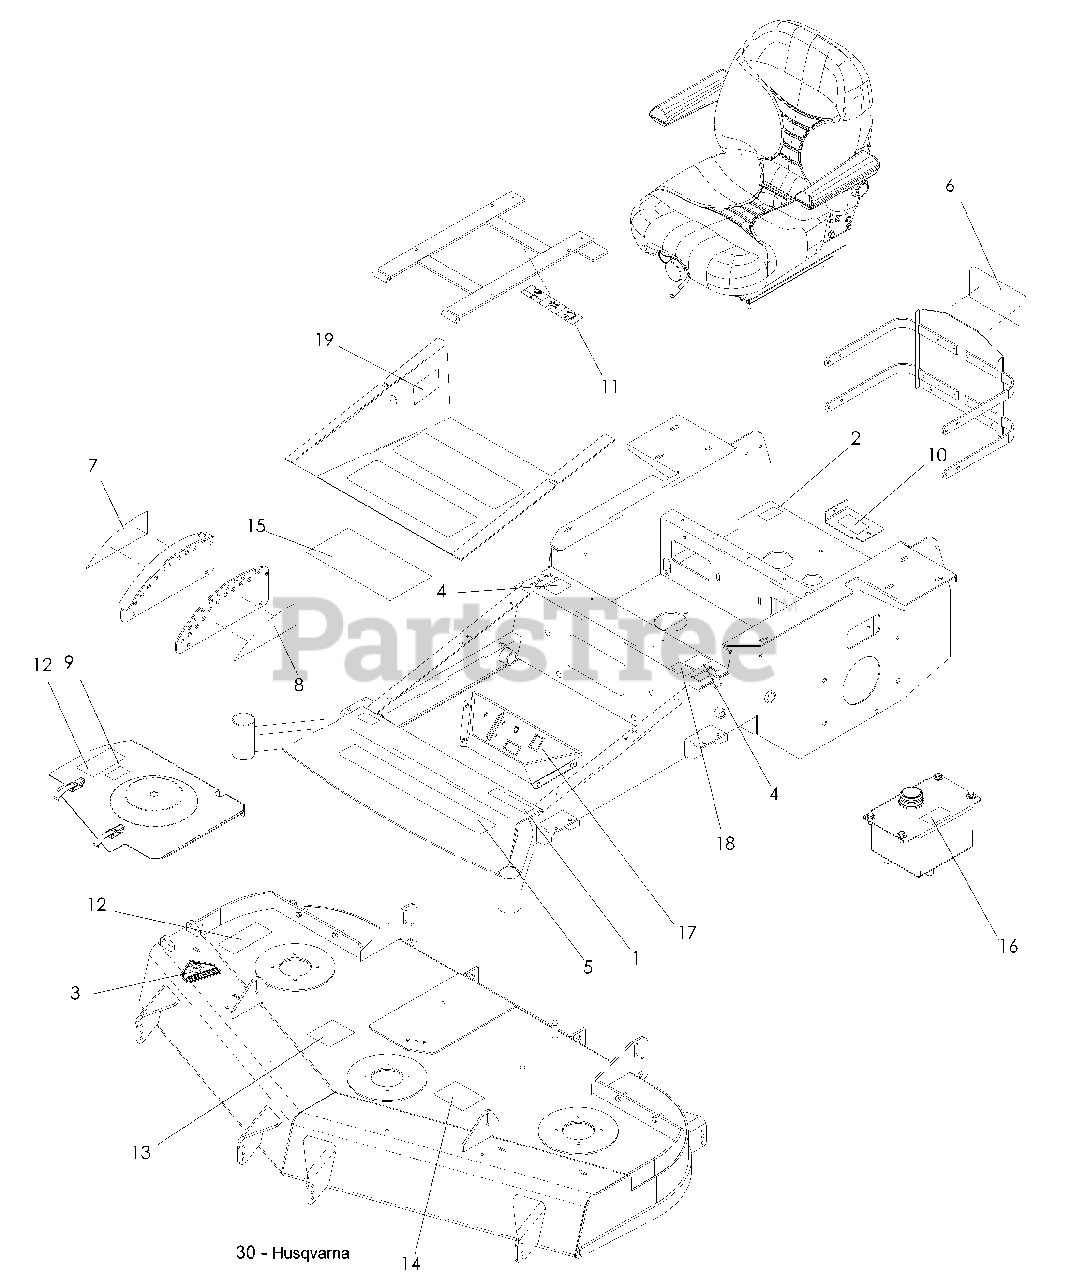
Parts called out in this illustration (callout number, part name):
1	DECAL, LZ5227
2	DECAL, PROP 65
3	DECAL, WARNING
4	DECAL, MOTION CONTROL
5	DECAL, HUSQVARNA
6	DECAL, HUSQVARNA CRWN
7	DECAL, HEIGHT INDICATOR
8	DECAL, HEIGHT INDICATOR
9	DECAL, NO STEP
10	DECAL, DANGER BELT DR
11	DECAL, BATTERY WARNING
12	DECAL, SEVERING
13	DECAL, ANTI-SCALP
14	DECAL, BELT ROUTING
15	DECAL, SERVICE
16	DECAL, OIL TANK
17	DECAL, CONSOLE
18	DECAL, TRACKING
19	DECAL, WARNING
